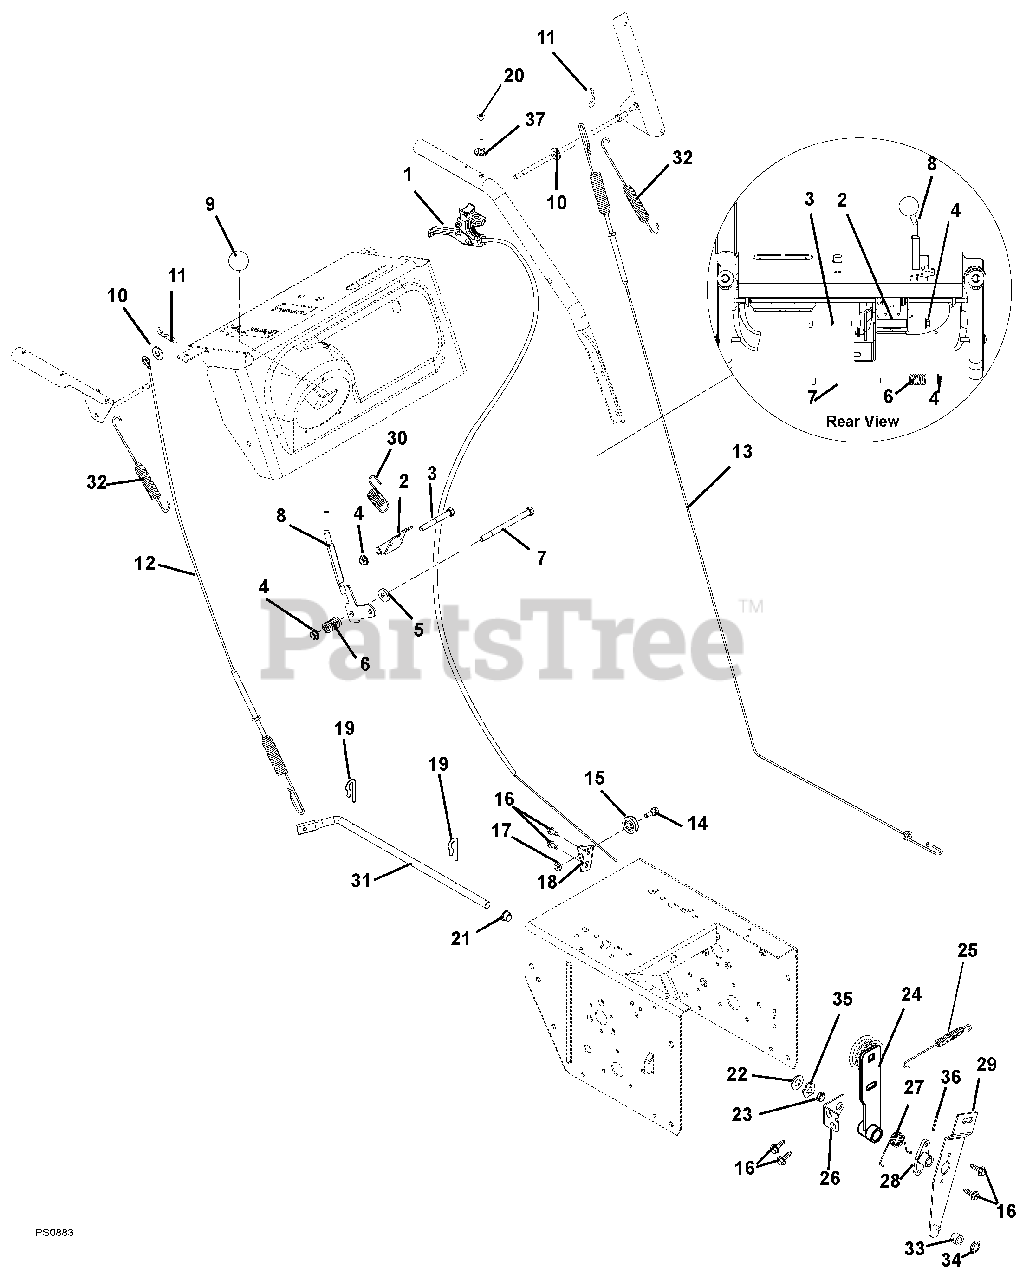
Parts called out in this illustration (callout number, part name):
1	Cable, Trigger Differential
2	Arm, Interlock
3	Bolt, Hex .38-16 x 3.00 Grade 5
4	Nut, Locking Top Flange .38-16
5	Washer, Flat Steel .406 x 1.00 x .188
6	Spring, Compression
7	Bolt, Hex .38-16 x 5.00 Grade 5
8	Lever, Shift
9	Knob, Ball Black
10	Washer, Flat Steel .28 x .62 x .065
11	Pin, Hair Internal .06 x .18 x .77
12	Cable, Attachment
13	Cable, Traction
14	Bolt, Shoulder .375 x .375 x .25-20
15	Pulley, Cable
16	Screw, Tap .25-20 x .50
17	Nut, Locking Top Flange .25-20
18	Bracket, Cable Pulley
19	Clip, Spring
20	Screw, Machine .25-20 x 1.50 Oval Head
21	Bushing, Polyliner .50 Split
22	Washer, Flat Steel .531 x 1.06 x .095
23	Bushing, Polyliner .50 Snap-in
24	Arm, Idler Traction
25	Spring, Tension
26	Bracket, Support
27	Spring, Torsion
28	Hub, Brake Arm
29	Arm, Idler Attachment
30	Spring, Tension
31	Arm, Attachment
32	Spring, Tension
33	Bushing,Sleeve
34	Ring, Retaining External .250 x .010
35	Wave Washer
36	Pin, Roll .125 x 1.00
37	Washer, Locking, Internal .250
